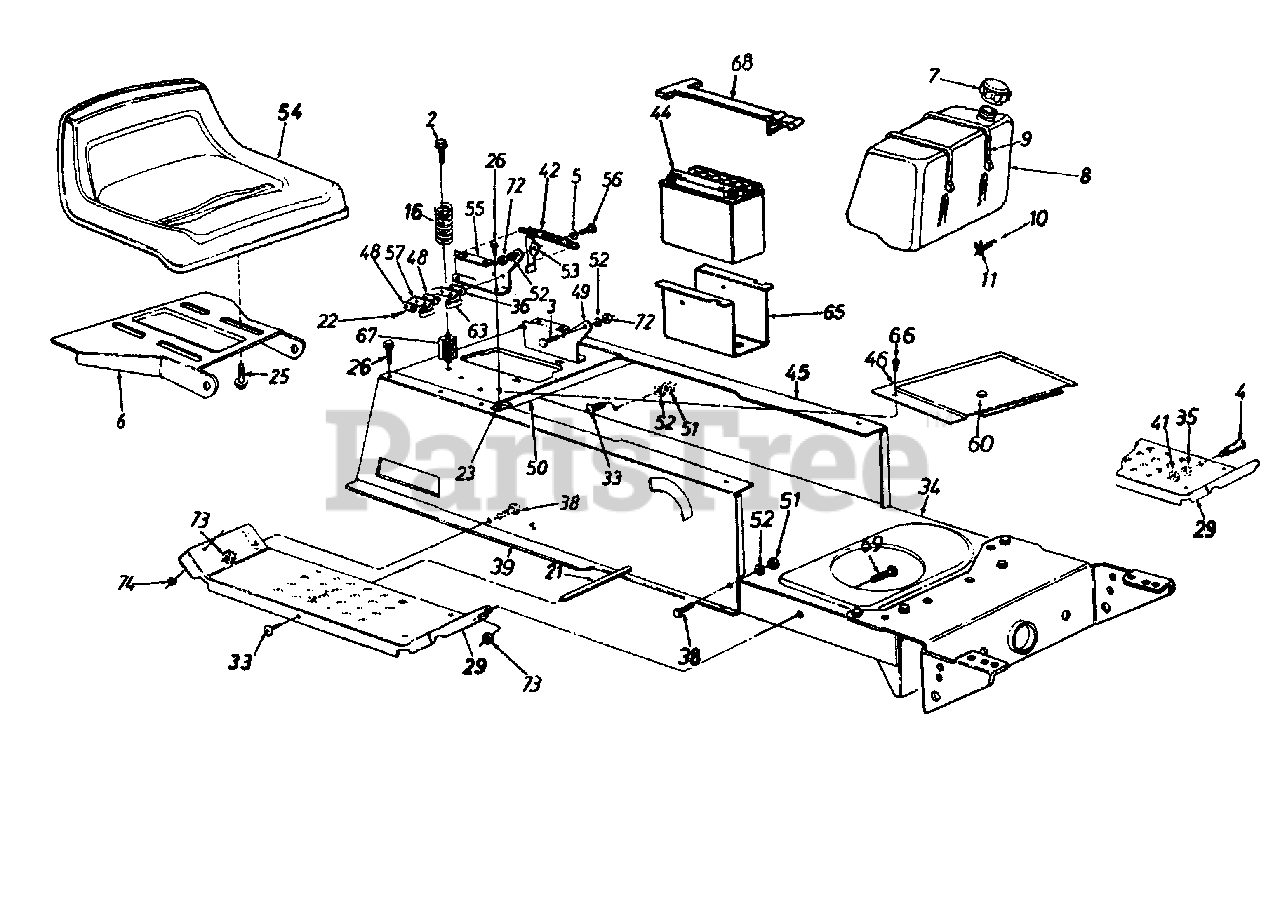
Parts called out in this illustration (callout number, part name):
2	Hex Wash. Hd. Tap Scr. 5/16-18 x 3.25" Lg.
3	Shld. Bolt .437" Dia. x .162"
4	Shld. Bolt .50" Dia. x .84"
5	Spr-Wash. .445" I.D. x .75
7	Fuel Cap
8	Fuel Tank
9	Tie Strap
10	Fuel Line
11	Hose Clamp
16	Compression Spring
21	Running Board Rod
22	Hex Wash. Hd. AB-Tap Scr.#8 x .50" Lg:
23	Speed Nut #10Z
25	Hex Tap Scr. 3/8-16 x .62" Lg.
26	Hex Wash. Hd. AB-Tap Scr. 5/16 x .75" Lg.
35	L-Wash. 3/8" I.D.
36	Insulator Boss Plate
38	Hex Bolt 5/16-18 x .75" Lg.
39	Upper Frame-R.H.
41	Hex Nut 3/8-16 Thd.
42	Extension Spring 5.31" Lg.
44	12-V Battery
45	Upper Frame-L.H.
52	L-Wash. 5/16" I.D.
53	Seat Lift Brkt.
54	Seat
56	Shld. Bolt .437" Dia. x .268"
57	Spring Switch (Seat)
60	Snap Bushing
63	Safety Switch (Seat)
66	Truss Mach. B-Tap Scr.#10 x .5" Lg.
67	Spring Spacer
68	Battery Retainer Strap
69	Hex Bolt 5/16-18 x .75" Lg.
72	Hex Nut 5/16-18 Thd.
73	Hex Sems Nut 5/16-18 Thd.
74	Hex Sems Nut 1/4-20 Thd.
